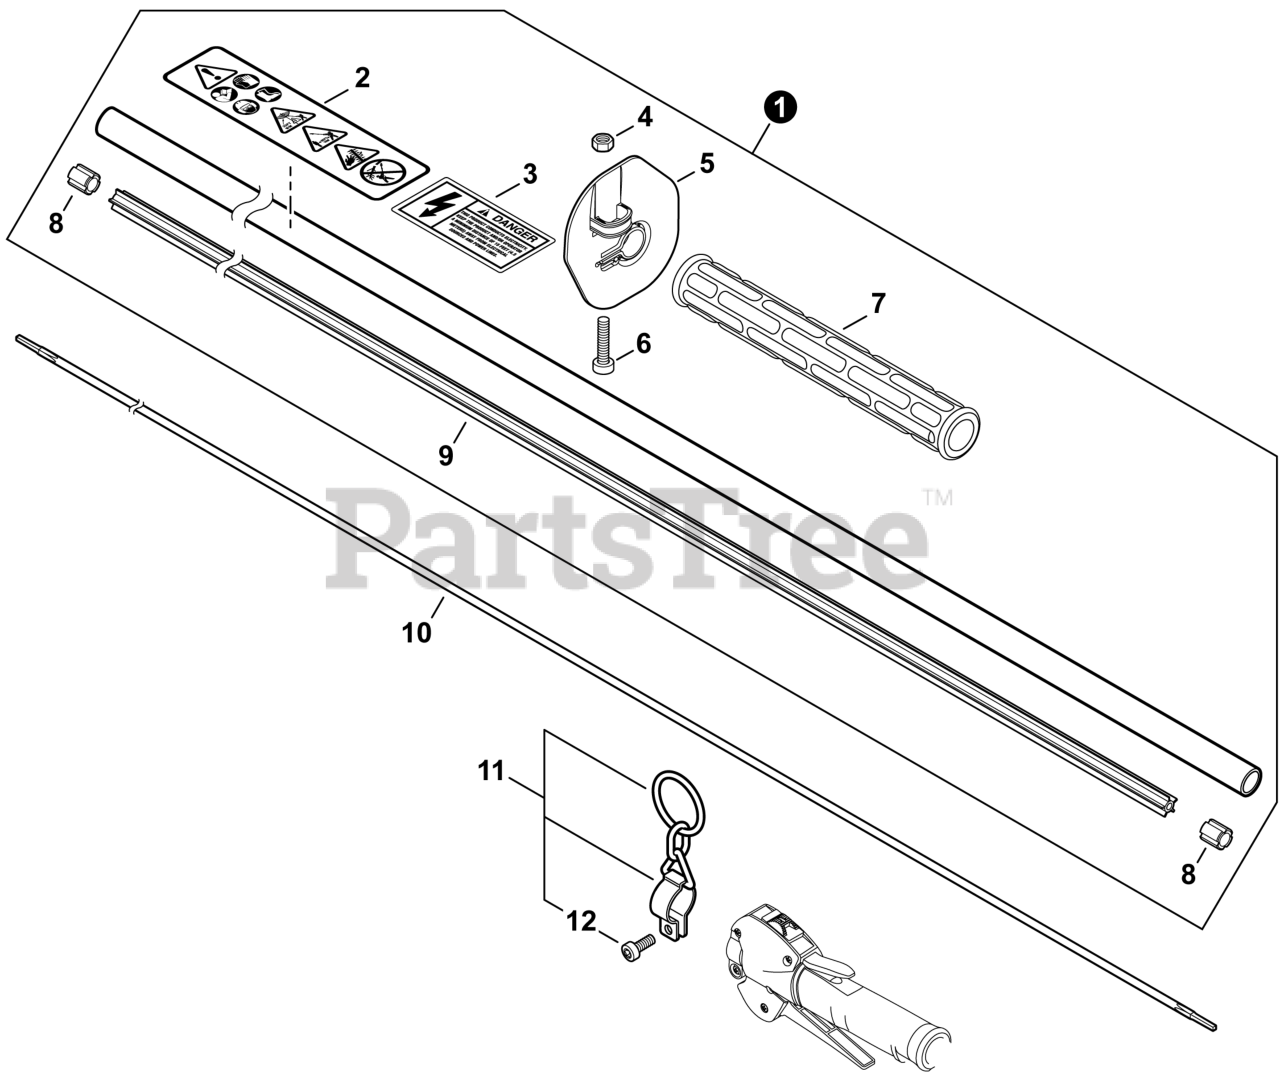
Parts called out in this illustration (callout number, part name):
1	MAIN PIPE ASSY
2	LABEL - CAUTION
3	LABEL - HIGH VOLTAGE
5	GUARD, HAND
6	BOLT, TORX 5×20
7	GRIP, FRONT
9	LINER, FLEXIBLE 21.6×1420
10	DRIVESHAFT - FLEXIBLE
11	HANGER SET, HARNESS
12	BOLT, TORX 5×12
